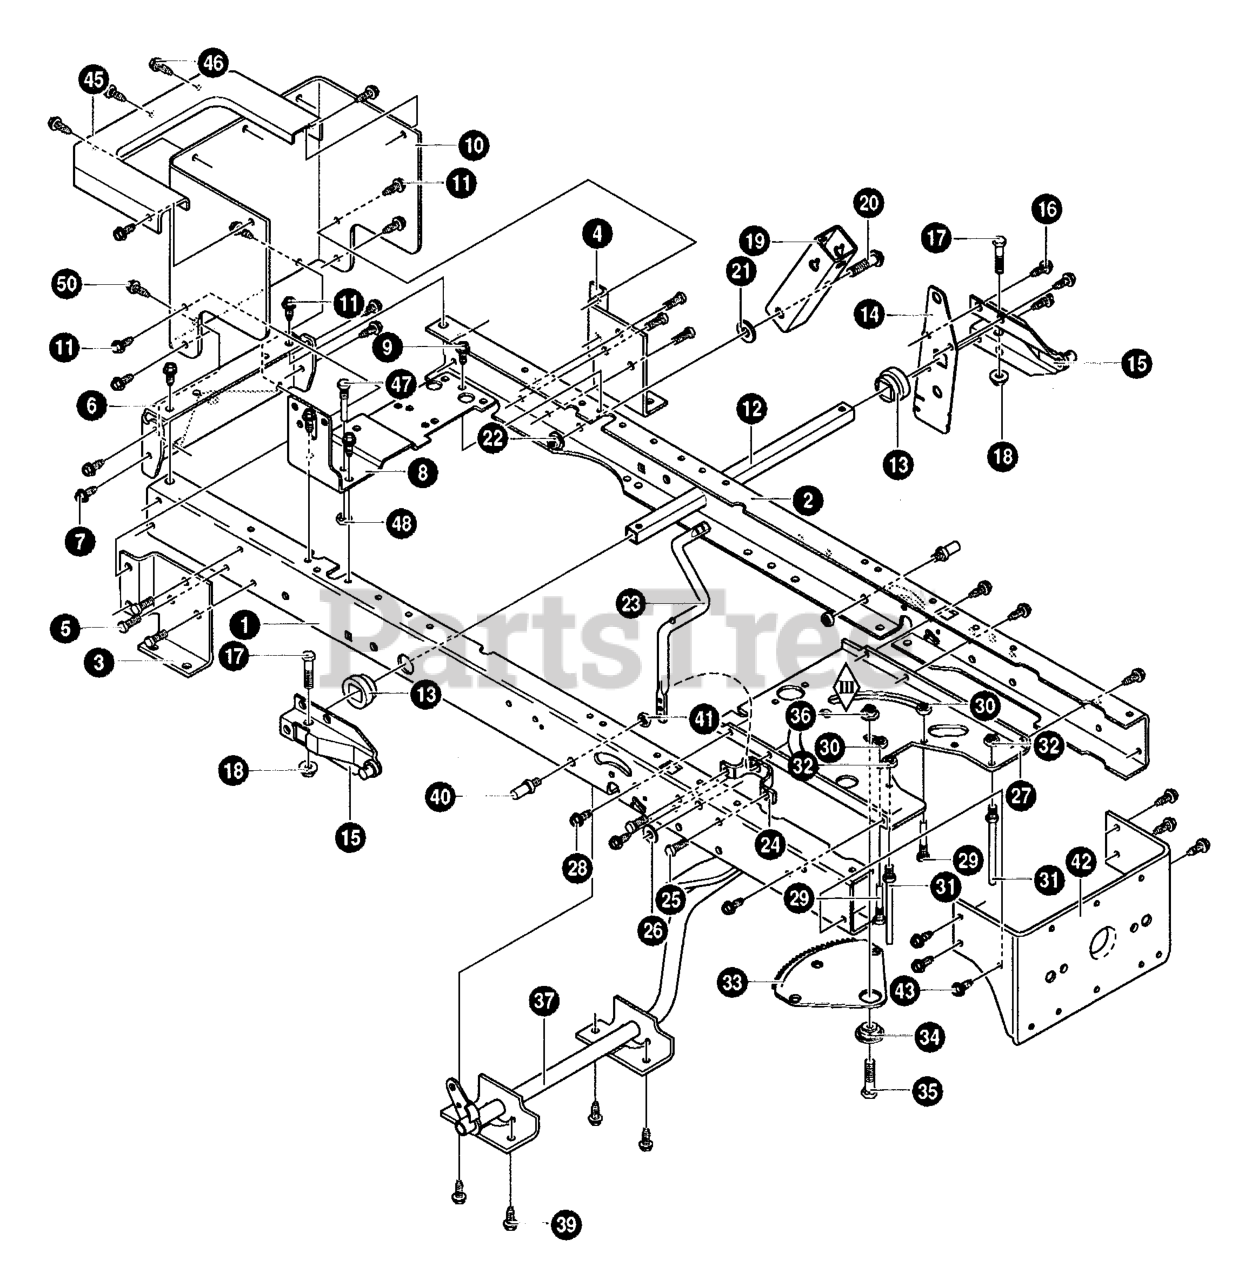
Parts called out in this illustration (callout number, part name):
1	FRAME, RAIL RH
2	FRAME, RAIL LH
3	BRACKET, TRANSAXLE RH
4	BRACKET, TRANSAXLE LH
5	SCREW, 5/16-18 x 0.75
6	HITCH PLATE
7	SCREW, 5/16-18 x 0.75
8	BRACKET, SHIFT RH
9	SCREW 5/16- 18X.75
10	PLATE, REAR
11	SCREW, 5/16-18 x 0.75
12	TUBE, LIFTER
13	BUSHING, LIFT TUBE
14	PLATE- LIFT ARM
15	ASSY LIFT ARM LEVER
16	SCREW, 5/16-18 x 0.50
17	SCREW, 5/16-24 x 1.25
18	NUT, 5/16- 24
19	BRACKET, PIVOT
21	FLATWASHER
22	NUT, 3/8- 16
23	CRANK, PTO (DRILLED)
24	BRACKET, BELLCRANK
25	SCREW, 5/16-18 x 0.75
26	FLATWASHER
27	PLATE, STEERING MOUNTING
28	SCREW, 5/16-18 x 0.75
29	SCREW GUIDE 5/16- 18
30	NUT, 5/16- 18
31	SCREW - GUIDE
32	NUT, 5/16- 18
33	SECTOR GEAR
34	BEARING, SECTOR GEAR
35	CAPSCREW, Hex Head, 5/16-18 x 1
36	NUT, 5/16- 8
37	ASSEMBLY, BRAKE LEVER
39	SCREW, 5/16-18 x 0.75
40	PIN, THREADED SHOULDER
41	NUT, 3/8- 16
42	BRACKET, HANGER REAR
43	SCREW, 5/16-18 x 0.75
45	TOP, REAR PLATE
46	SCREW 10- 24X.5
47	SCREW GUIDE 5/16- 18
48	NUT, 5/16- 18
50	SCREW, 3/8- 16X1.25
